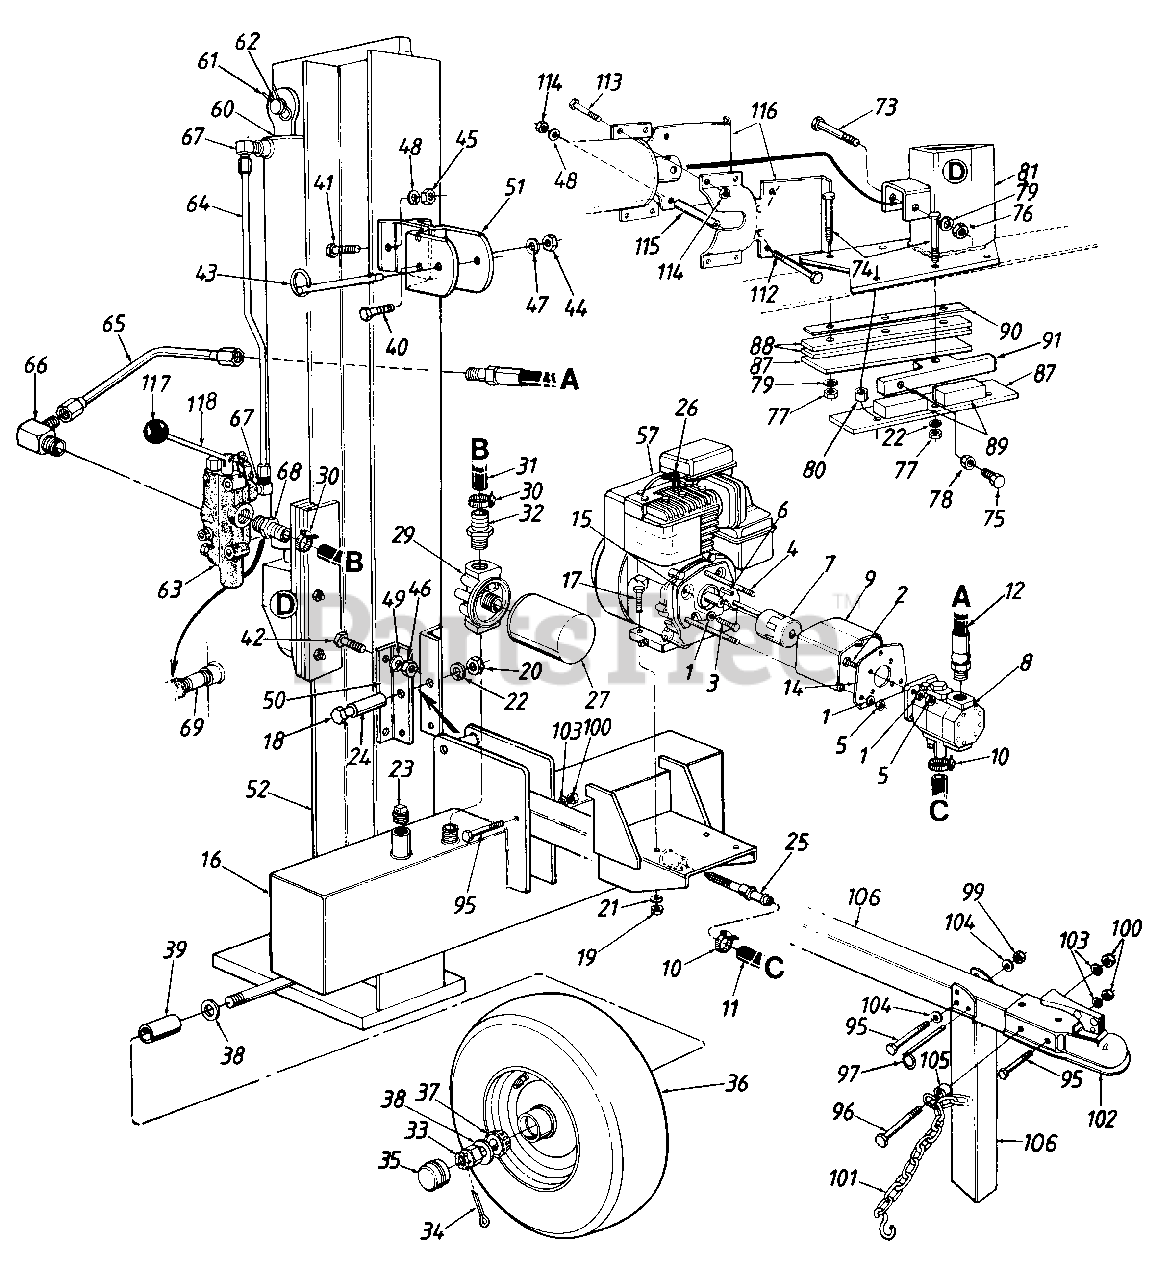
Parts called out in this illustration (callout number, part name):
1	L-Wash. 5/16" I.D.
2	Hex Bolt 5/16-24 x 1" Lg.
3	Hex Bolt 5/16-24 x .62" Lg.
4	Hex Bolt 5/16-24 x 4" Lg.
5	Hex Nut 5/16-24 Thd.
6	Sq.-Key 3/16 x .75
7	Flexible Coupling
8	Two Volume Pump
9	Coupling Shield
10	Hose Clamp 5/8"
11	Suction Hose 1" I.D.
12	High Pressure Hydraulic Hose 56"
16	Tank Ass'y. Complete
17	Hex Bolt 5/16-24 x 1.75" Lg.
18	Hex Bolt 1/2-20 x 4" Lg.-Gr. 5
19	Hex Nut 5/16-24 Thd.
20	Nut 1/2 BL NF-20
21	L-Wash. 5/16" I.D.*
22	L-Wash. 1/2" I.D.
23	Pipe Plug
24	Pivot Bushing .75" O.D.
25	Strainer Ass'y.
26	Spark Plug Cover
27	Filter Element
29	Filter Head
30	Adjustable Hose Clamp
31	Return Hose 3/4" I.D. x 30" Lg.
32	3/4" Dia. Hose Barb
33	Hex Castle Nut 3/4-16 Thd.
34	Cotter Pin 5132"
35	Hub Cap
37	Roller Brg. 3/4"
38	Fl-Wash. .760" I.D. x 1.5" O.D.
39	Spacer .75" I.D. x 1.12" O.D.
40	Hex Bolt 5/16-24 x 1" Lg.*
41	Hex Bolt 3/8-16 x 1" Lg.-Gr. 5
42	Hex Bolt 7/16-20 x 1.25" Lg.- Gr. 5
43	Quick Release Pin
44	Hex Nut 5/16-24 Thd.
45	Hex Nut 3/8-16 Thd.-Gr. 5
46	Hex Patch L-Nut 7/16-20 Thd.
47	L-Wash. 5/16" I.D.
48	L-Wash. 3/8" I.D.
49	L-Wash. 7/16" I.D.
50	Beam Mtg. Plate
51	Beam Latch Bracket
52	Vertical Beam Ass'y.
57	5 H.P. Engine
60	Hydraulic Cylinder 4" Dia.
61	External Cotter Pin
62	Cylinder Mtg. Pin
63	Control Valve-3000 PSI
64	Metal Pressure Tube 1/2" O.D.
65	Pressure Tube 1/2" Dia.
66	90ø Solid Male Adapter
67	90ø Solid Male Adapter
68	3/4" Dia. Hose Barb
69	Pipe Nipple 1/2 NPT
73	Bolt 1/2 x 3
74	Hex Bolt 1/2-20 x 2.75" Lg.- Gr. 8
75	Hex Bolt 3/8-24 x 1.5" Lg.
76	Hex L-Nut 1/2-20 Thd.
77	Nut 1/2 BL NF-20 Thd.
78	Hex Jam Nut 3/8-24 Thd.-Gr. 5
79	L-Wash. 1/2" I.D.
80	Spacer 1/2" I.D. x 314" O.D.
81	Wedge Mtg. Ass'y.
87	Pusher Back Plate
88	Fixed Side Gib
90	Adj. Gib Shim 10" Lg.
95	Hex Bolt 3/8-16 x 3" Lg.-Gr. 8
96	Hex Bolt 3/8-16 x 3.25" Lg.- Gr. 8
97	Quick Release Pin
99	Hex L-Nut 3/8-16 Thd.
100	Hex Nut 3/8-16 Thd.
101	Chain-Tow Hitch
102	Hitch Coupler
103	L-Wash. 3/8
104	Fl-Wash. .406" I.D. x .75
105	Spacer .38" I.D. x .625" O.D.
106	Tongue Tube
112	Hex Bolt 3/8-16 x 5.5" Lg.
113	Hex Bolt 3/8-16 x 2" Lg.-Gr. 5
114	Hex Insert L-Nut 3/8-16 Thd.
115	Spacer 4" Lg.
118	Control Handle
